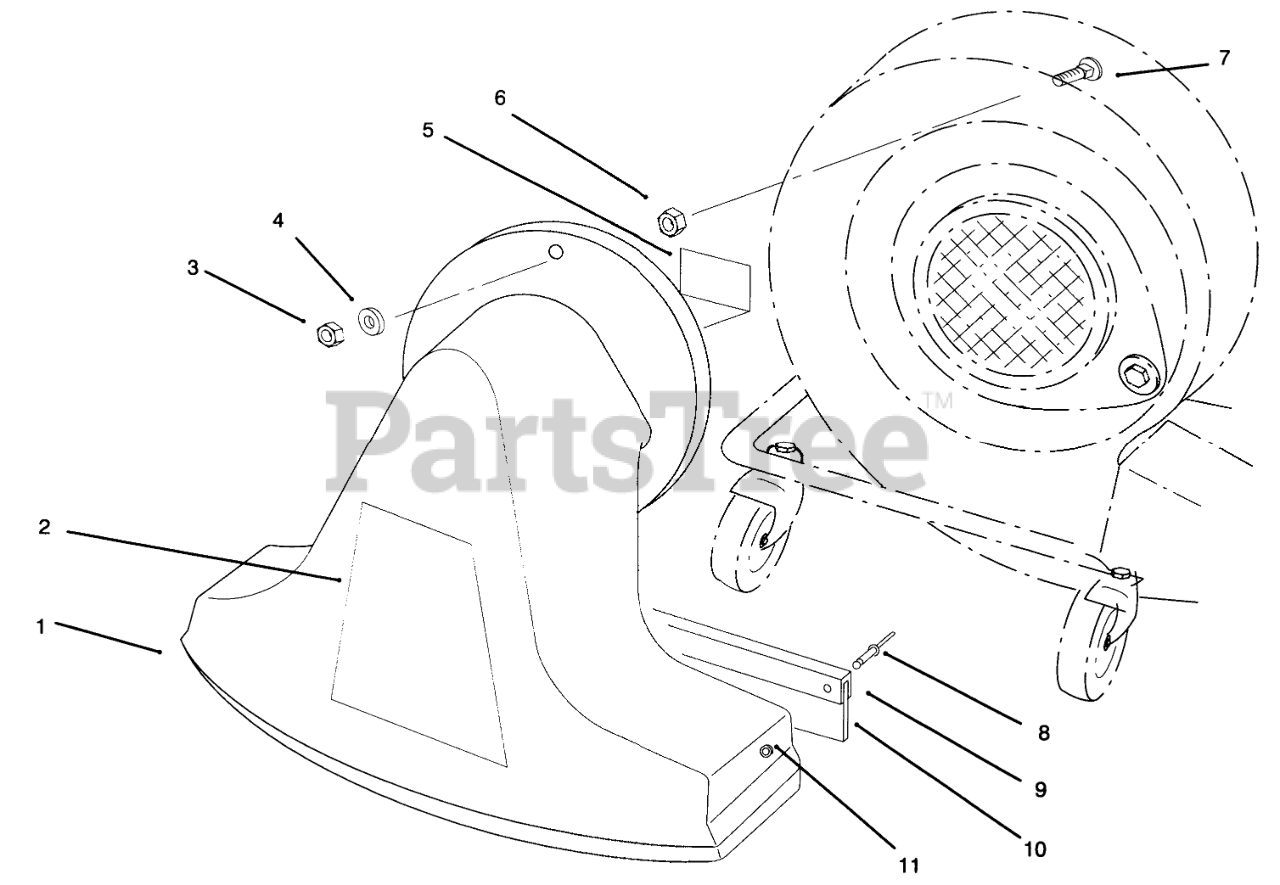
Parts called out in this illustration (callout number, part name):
1	Snout Assembly (Incl. Ref #7-10)
2	DECAL-VACUUM SP
3	NUT-LOCK, NI
4	Washer
5	DECAL-CAUTION, BAG
6	NUT-FLANGE
7	BOLT-CARR
8	POP RIVET 3/16X.375LG
9	Clamp-Flap
10	FLAP-RUBBER
11	WASHER-FLAT
